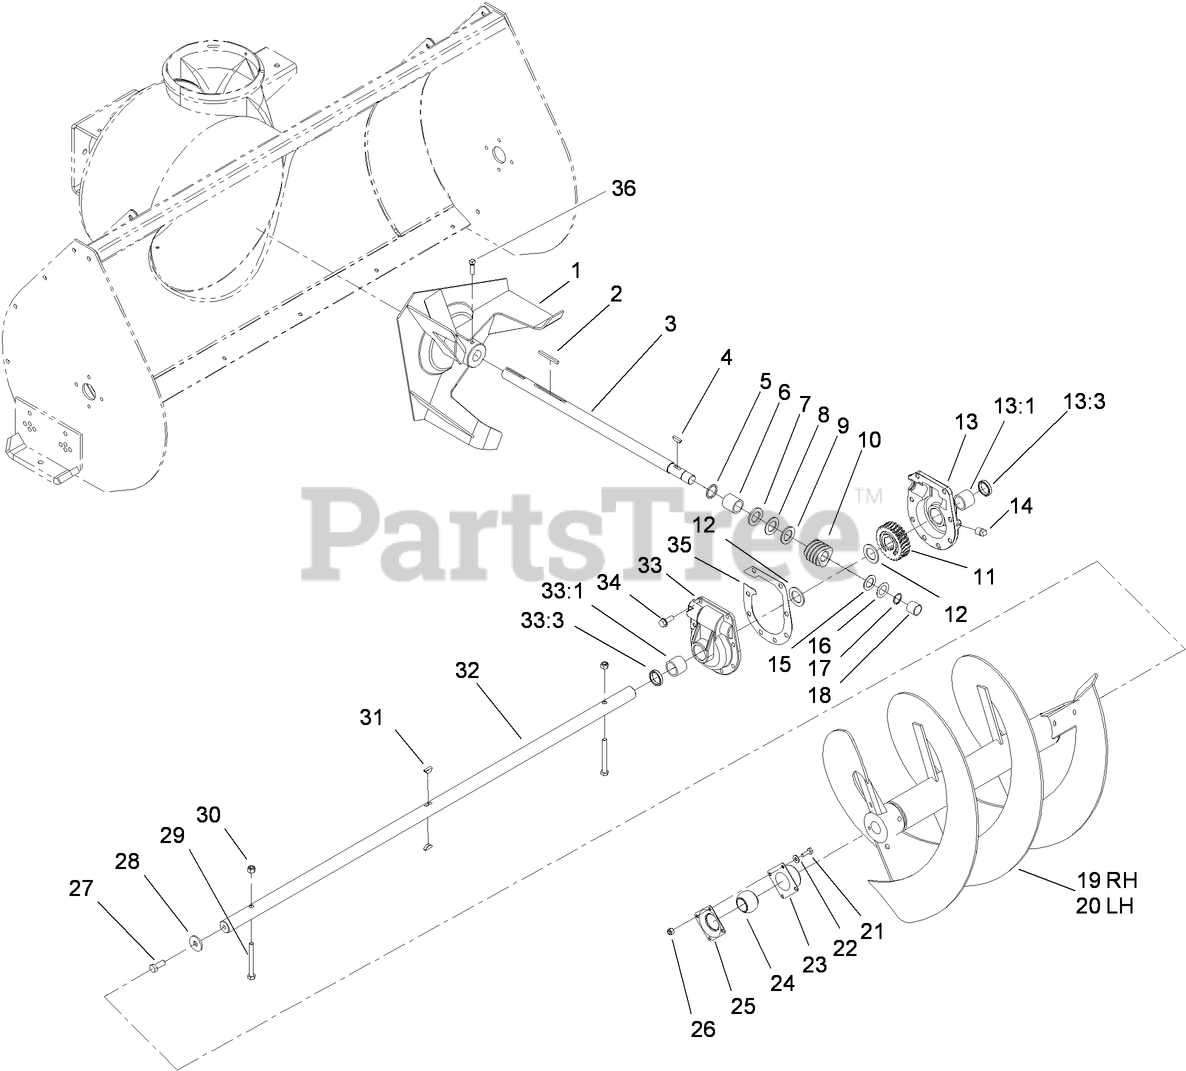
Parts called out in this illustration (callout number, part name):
1	IMPELLER ASM
3	SHAFT-IMPELLER
4	KEY-WOODRUFF
5	RING-QUAD
6	BUSHING-SPECIAL
7	WASHER-THRUST
8	BEARING-THRUST
9	THRUST-WASHER
11	GEAR-WORM, 27T
12	WASHER-THRUST
13	LH GEAR CASE ASM
13:1	BUSHING
13:3	SEAL-OIL
14	PLUG-PIPE, SQH
15	WASHER-THRUST
16	WASHER-SHIM
17	Ring-Snap
18	BUSHING
19	RH AUGER ASM
21	SCREW-HH
22	WASHER-FLAT
23	BEARING-FLANGE, FRONT
24	BEARING
25	BEARING-FLANGE, REAR
26	NUT-LOCK, NI
27	SCREW-HH, LOCK
28	WASHER
29	SCREW-HH
30	NUT-LOCK, NI
31	KEY-WOODRUFF
32	SHAFT-AUGER
33	RH GEAR CASE ASM
33:1	BUSHING
33:3	SEAL-OIL
34	SCREW-TAPTITE
35	GASKET-GEAR BOX
36	SCREW-SET, SQH
